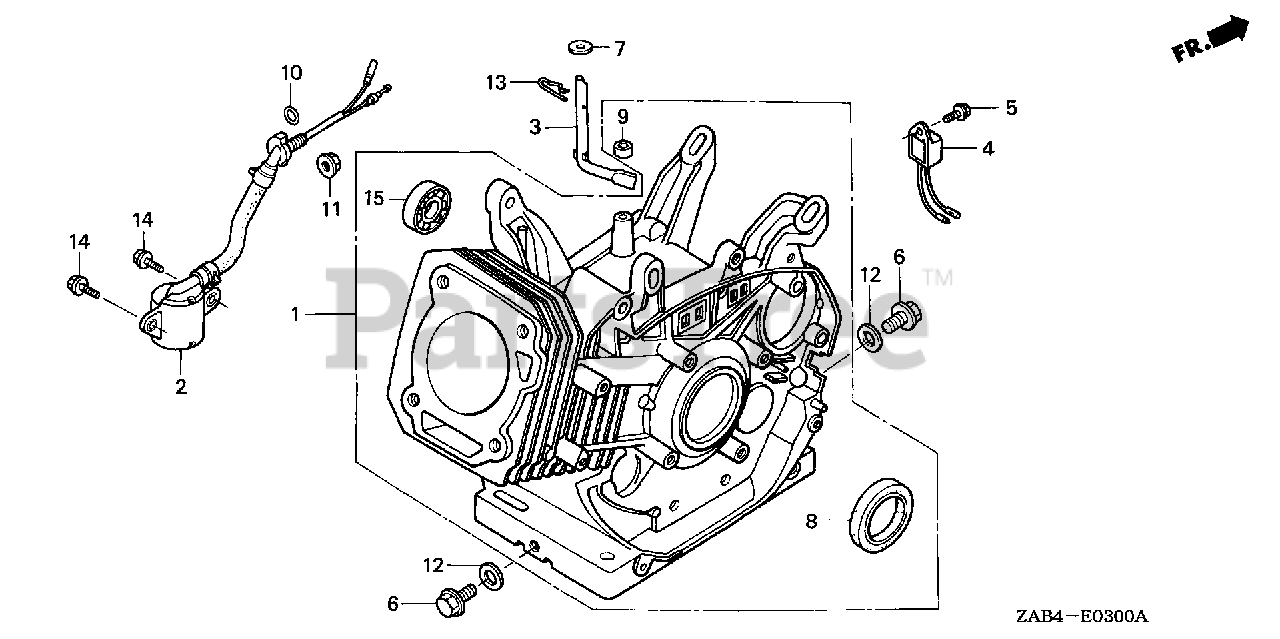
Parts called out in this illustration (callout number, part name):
1	CYLINDER ASSY.
2	SWITCH ASSY., OIL LEVEL
3	SHAFT, GOVERNOR ARM
4	ALERT UNIT, OIL
5	BOLT, FLANGE (6X12) (CT200)
6	BOLT, DRAIN PLUG
7	WASHER (8.2X17X0.8)
8	OIL SEAL (35X52X8)
9	OIL SEAL (8X14X5)
10	O-RING (13.5X1.5) (ARAI)
11	NUT, FLANGE (10MM)
12	WASHER, DRAIN PLUG (12MM)
13	PIN, LOCK (10MM)
14	BOLT, FLANGE (6X12)
15	BEARING, RADIAL BALL (6202)
